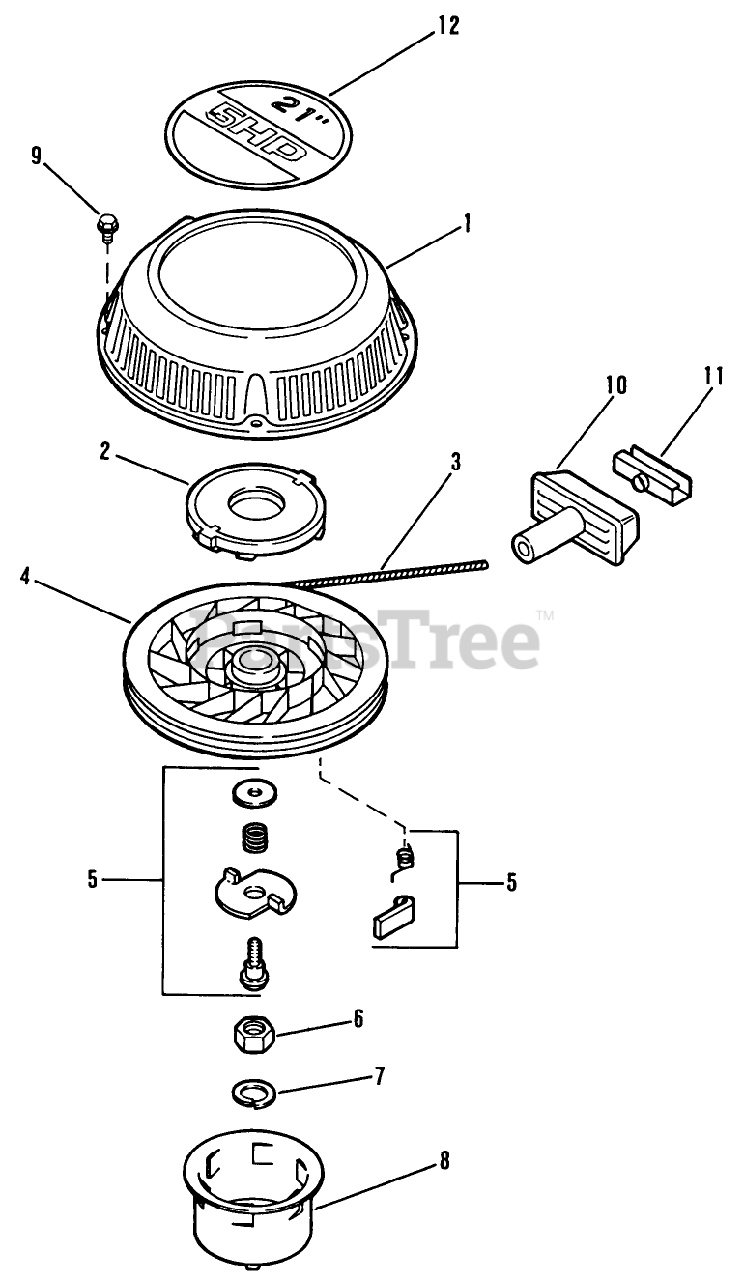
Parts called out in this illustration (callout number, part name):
3	ROPE - NATURAL (#5.5, 97" LONG)
4	PULLEY
5	DOG KIT
6	NUT
8	HUB STARTER SM
9	SCREW SEMS SM
11	CLIP-STARTER
